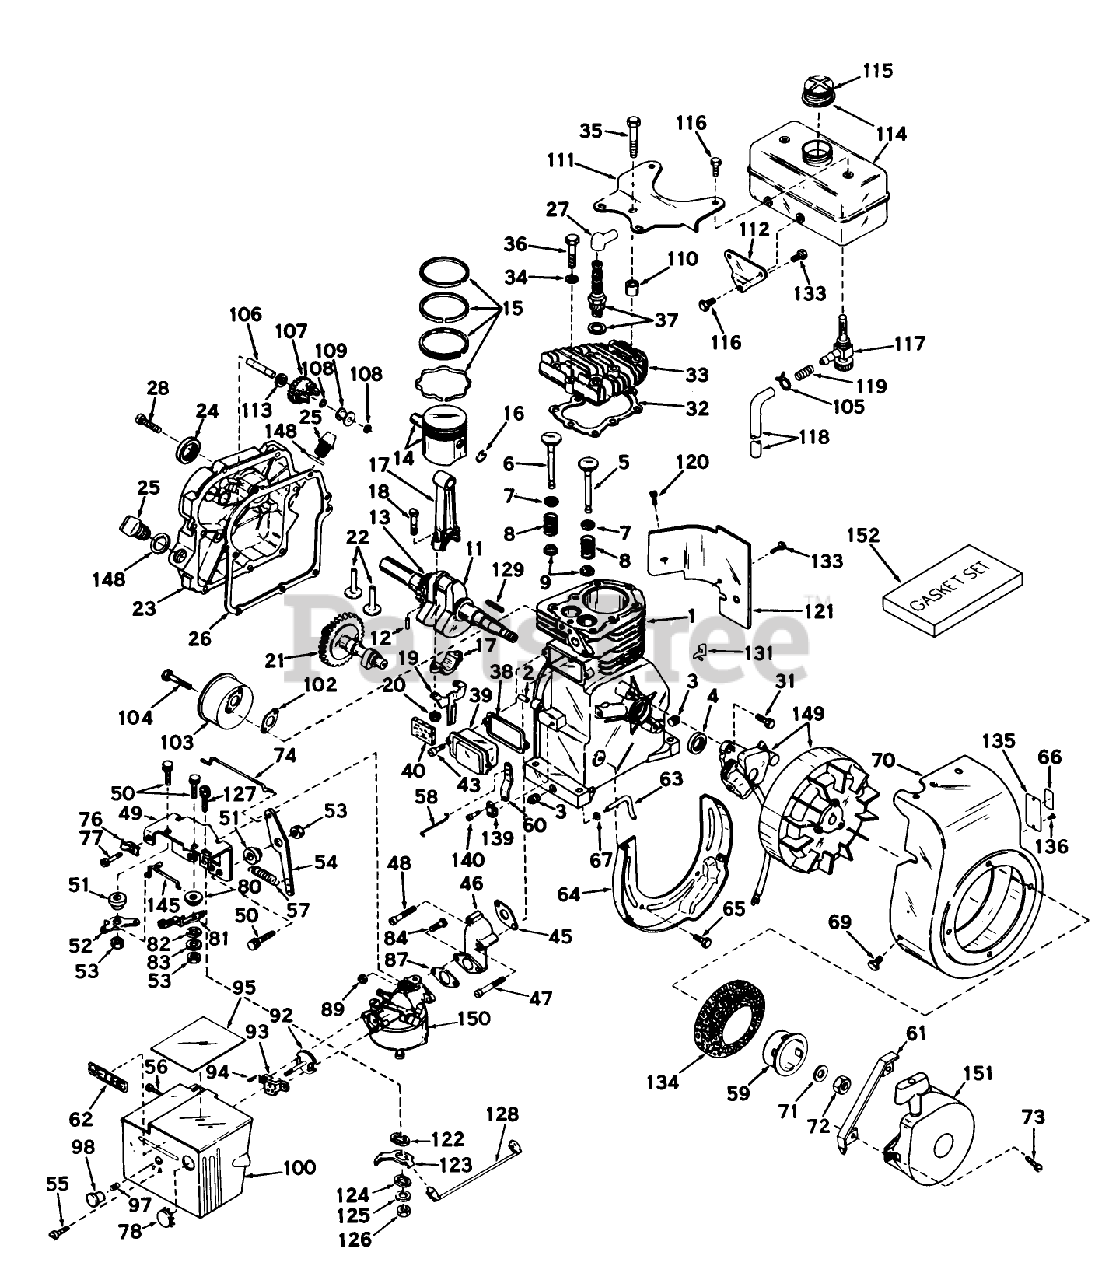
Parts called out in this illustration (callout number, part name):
1	Cylinder Assy., (Incl. Nos. 2, 3 4)
2	Pin-Dowel
3	Plug-Drain, Oil (SQH 1/4-18)
4	OIL SEAL
5	Valve, Intake (Incl. Ref. #38, 39 40) (Std.)
5	Valve, Intake(1/32"overs.)(Incl. Ref. 8, 9 10)
6	Valve, Exhaust (Standard)(Incl. Ref. 8, 9 10)
6	Valve, Exhaust (1/32" Overs.(Incl. Ref. 8, 9 10)
7	Cap-Upper Valve Spring
8	Spring-Valve
9	Cap-Valve, Spring
11	Crankshaft Assy. (Incl. Ref. 12 13)
12	Pin, Groove
13	Gear, Crankshaft
14	Piston Pin Assy. (Incl. 2 of No. 16)(Standard)
14	Piston Pin Assy. (Incl. 2 of No. 16)(.010 oversize)
14	53020 ADN. TO 28594
15	Piston Ring Set Std.
15	Piston Ring Set .010 O.S.
15	Piston Ring Set .020 O.S.
16	Ring-Retaining, Piston Pin
17	Rod Assy., Connecting (Incl. Ref. 18, 19 20)
18	Bolt, Connecting
19	53020/22 GIL.HYDRO
20	LOCKNUT
21	Camshaft
22	Hook-Battery
23	Cover, Cylinder (Incl. Nos. 24 106)
24	Seal, Oil
25	Plug-Fill, Oil
26	Gasket-Cylinder Cover
27	Cover-Spark Plug
28	Screw
31	Screw
32	Gasket-Cylinder Head
33	CYLINDER HEAD
34	Washer
35	Screw
36	Screw
37	SPARK PLUG
38	Gasket Breather
39	Breather Assembly (Incl. Nos. 52 84)
40	Element-Breather
43	Screw
45	Gasket-Intake
46	INTAKE PIPE
47	Screw
48	Screw
49	Bracket, Speed Control
50	SCREW, HEX WASHER HD.
51	Bushing
52	Lever, RPM Adjusting
53	Nut
54	Lever, Bell Crank
55	752 SICKLE BAR MOWE
56	Screw, Rd. Hd. Sheet Metal
57	Spring-Extension
58	Jet-Main
59	Starter Cup
60	Lever-Governor
61	Guard, Starter
62	Decal, Choke
63	Rod-Governor
64	Baffle, Blower Hsg.
65	Screw (1/4-20x19/32)
66	Decal, Instruction
67	Washer-Flat
69	Screw
70	Housing,Blower
71	Washer
72	Hex Nut
73	Screw
74	Link, Bell Crank
76	Conduit
77	Screw (10-32 x 3/8)
78	Plug
80	Bushing Control Lever
81	Lever, Control
82	Washer
83	Washer, Flat
87	Gasket
89	Nut and Lock Washer (1/4-28)
92	Plate, Choke
93	Bracket-Choke
94	Screw (10-32 x 1/2)
95	Decal, Operating
97	Spring, Compression
98	Knob, Choke
100	Capscrew
102	Gasket Exhaust
103	Muffler
104	Screw, Hex Hd. Cap
105	Clamp-Line, Fuel
106	Shaft-Governor
107	Governor Gear ASM
108	Ring-Retaining
109	Spool-Governor
110	pacer
111	Bracket, Fuel Tank-Upper
112	Bracket, Fuel Tank-Lower
113	Washer-Flat
114	Tank Assy., Fuel (Incl. No. 115)
115	Cap, Fuel Tank
116	Screw
117	Fitting Shut-off, Fuel
118	Line-Fuel
119	Spring, Coil
120	Screw
121	Extension-Blower
122	Washer, Insulating
123	Terminal
124	Washer, Insulating
125	Washer, Flat
126	Nut
127	Screw, Hex Slotted Hd.
128	Wire, Ground
129	Key Flywheel
131	Clip-Wire
133	Screw (1/4-20x19/32)
134	Screen, Air
135	IDENTIFICATION PLATE
136	DRIVE STUD
139	Clamp-Lever, Governor
140	Screw
145	Link, RPM Adjusting
148	Gasket
149	Magneto
150	Carburetor
151	Starter, Rewind
152	Gasket Set
